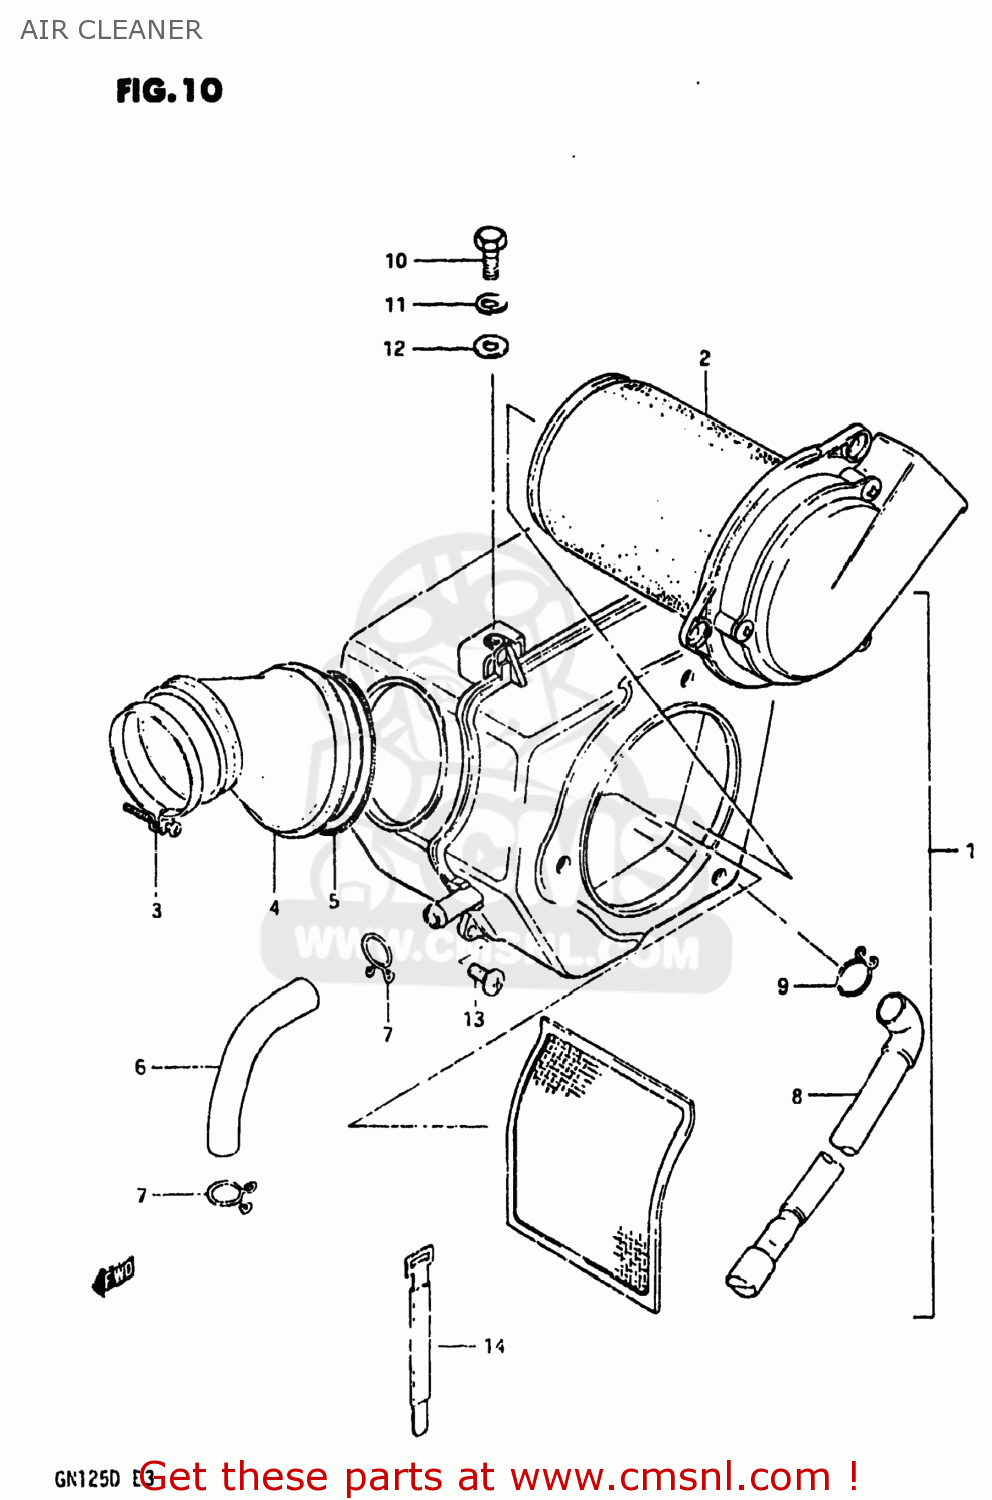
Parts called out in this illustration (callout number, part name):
1	CLEANER ASSEMBLY,AIR
2	FILTER,AIR CLEANER
3	CLAMP
4	TUBE,OUTLET
5	CLAMP,AIR CLEANER SIDE
6	TUBE,BREATHER
7	CLIP,BREATHER TUBE
8	DRAIN TUBE
9	CLIP
10	BOLT, UPPER
11	LOCK WASHER
12	WASHER
13	SCREW
14	CLAMP L:110
